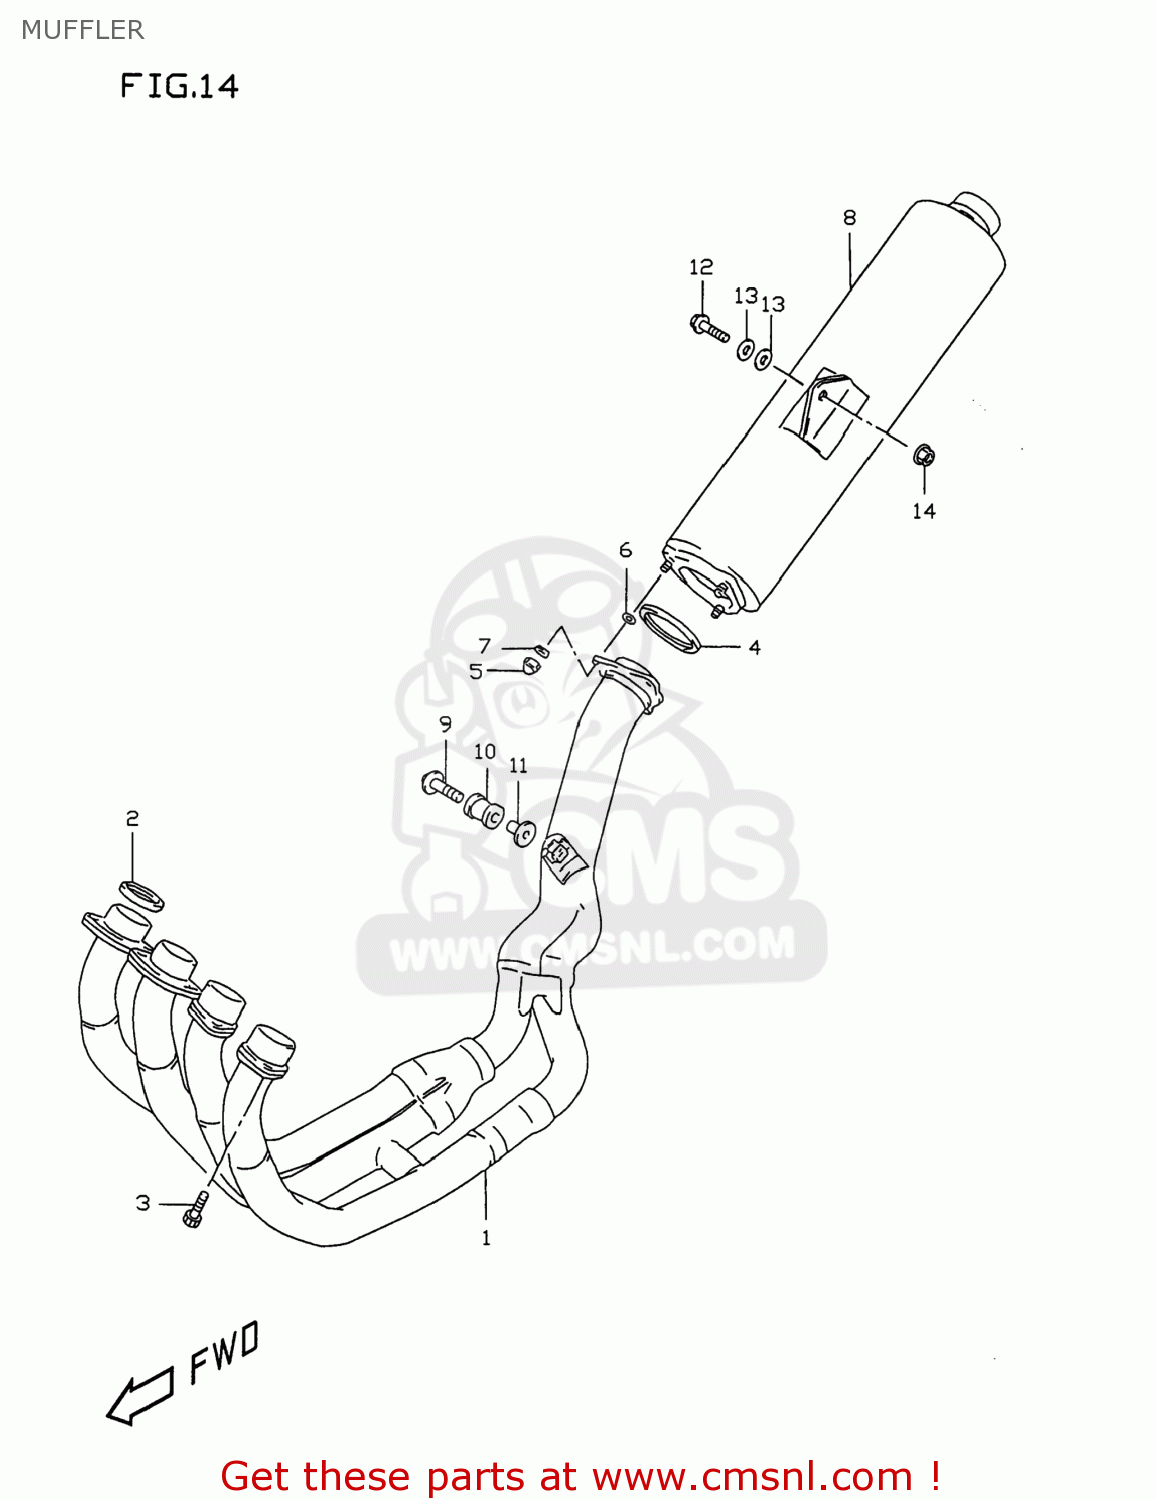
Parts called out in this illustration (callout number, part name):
1	EXHAUST COMP
2	GASKET,EXHAUST PIPE
3	BOLT
4	GASKET,MUFFLER JOINT
5	NUT
6	WASHER(8.5X18X1.6)
7	O RING(D:1.9,ID:7.8)
8	BODY,MUFFLER
9	BOLT 8X45
10	CUSHION
11	SPACER(8.6X12X24.2)
12	BOLT
13	WASHER (8.2X24X1.6)
14	NUT
